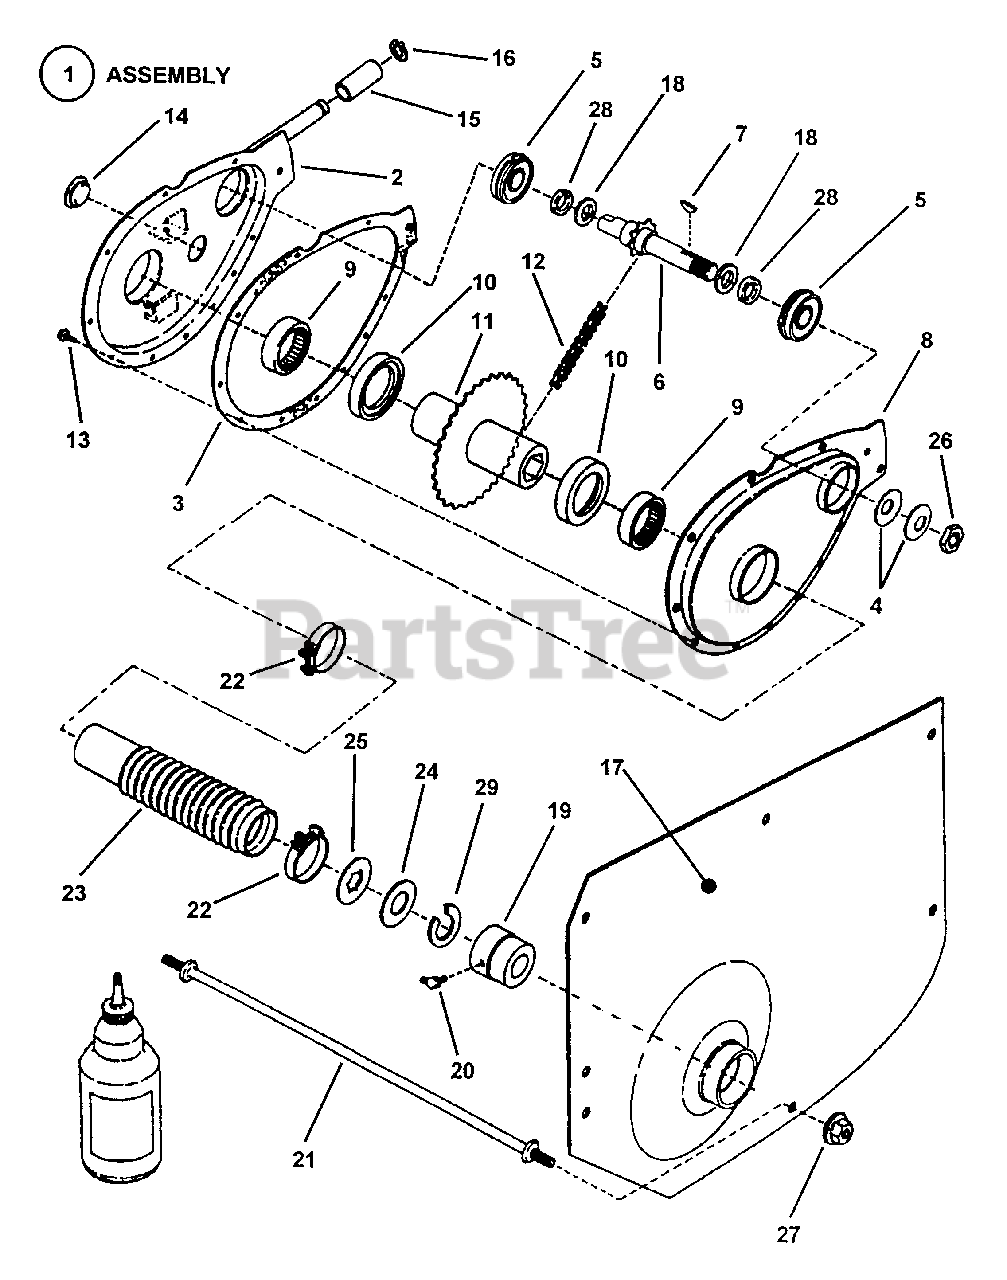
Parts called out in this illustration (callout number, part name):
1	ASSEMBLY, Chain Case
2	CASE, Sprocket
3	GASKET, Case Cover
4	WASHER, Belleville
5	BEARING, Ball
6	SPROCKET & SHAFT
7	KEY, 1/8 x 5/8" Woodruff
8	COVER, Chain Case
9	BEARING, Needle
10	WASHER, Nylon Thrust
11	HUB & SPROCKET
12	CHAIN
13	SCREW, #10-24 x 1/2" Hex Washer Self-Tap (Torx)
14	PLUG, Oil Fill & Check
15	ROLLER
16	RING, 1/2" External Retaining (Heavy Duty)
17	FENDER, Left Hand (1.628" internal diameter hole)
18	WASHER, Shim
19	BEARING, Left Hand Fender
20	FITTING, Lube
21	ROD, Cross-Tie
22	CLAMP, Boot
23	BOOT, Oil Seal
24	WASHER, Thrust Nylon
25	WASHER, Thrust
26	NUT, 5/8-18 Hex Lock
27	NUT, 5/16-24 Hex Flange Lock
28	O-RING
29	WASHER, Shim
